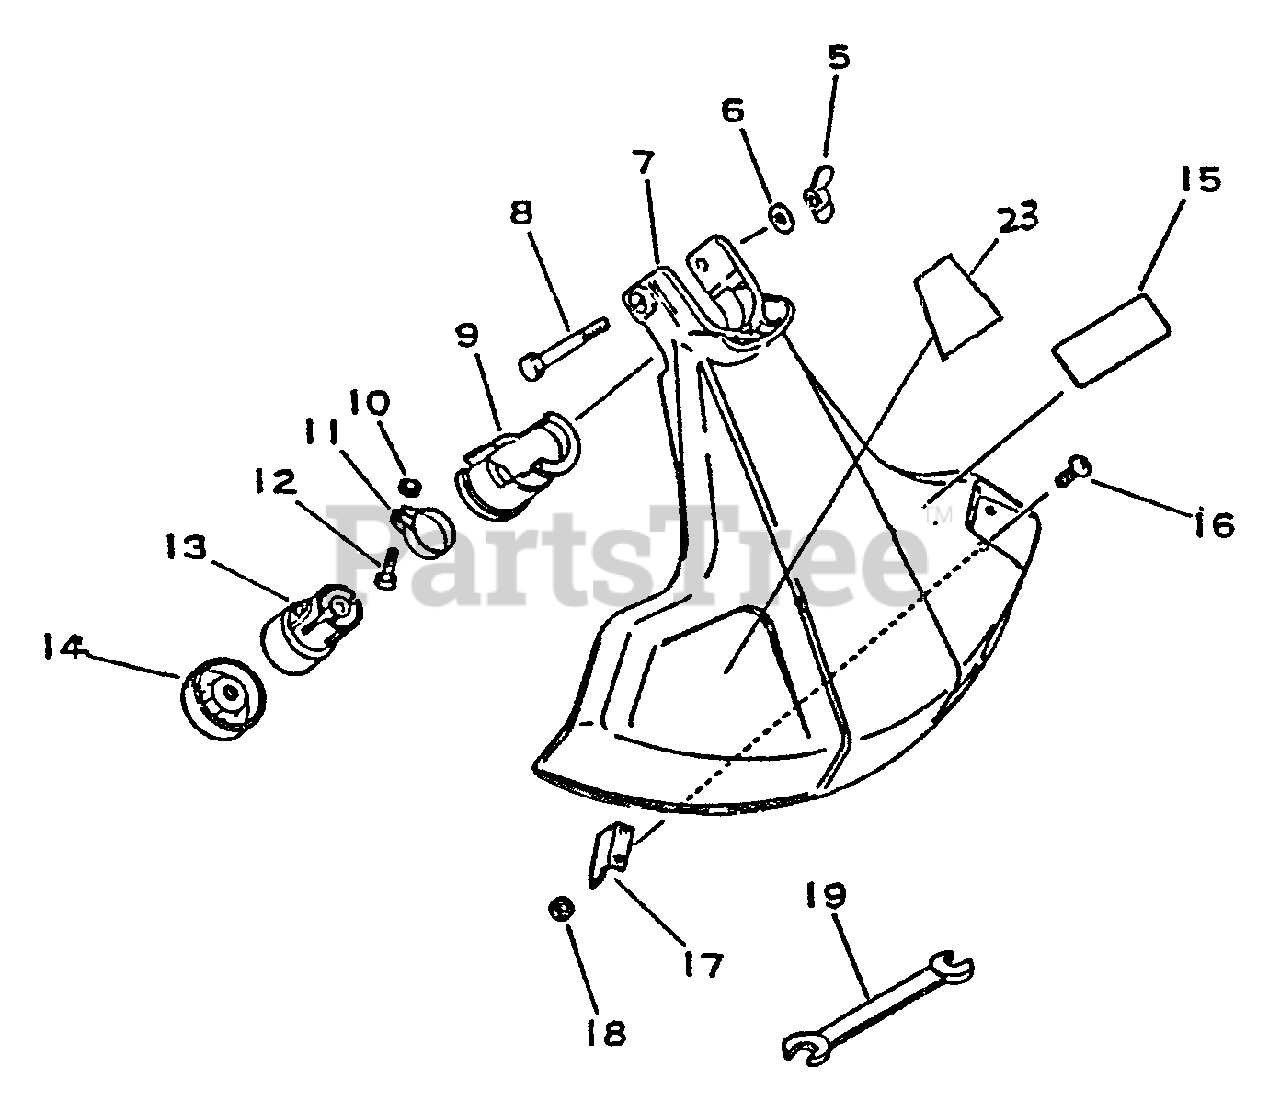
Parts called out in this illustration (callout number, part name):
5	NUT, WING 6
6	WASHER 6.5×11.5×0.8
7	SHIELD
8	BOLT - 6×50
9	BRACKET, BEARING CASE
10	NUT M5
13	GEAR CASE ASSY
14	PLATE, ADAPTER - UPPER
15	LABEL - ECHO
16	SCREW 5×16
17	CUTTER, LINE
18	NUT M5
19	SPANNER 8×10
23	LABEL, CAUTION
